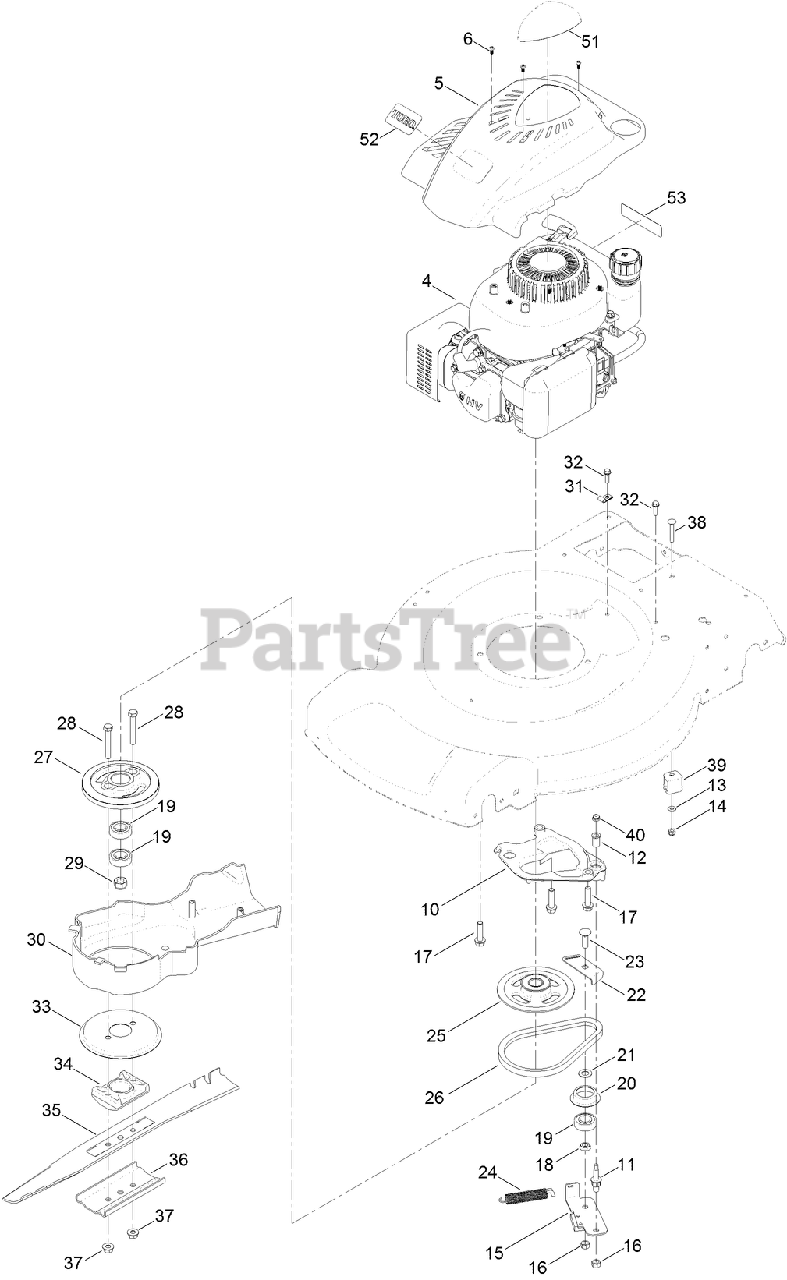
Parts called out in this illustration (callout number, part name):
4	ENGINE-1P65FC
5	SHROUD
6	SCREW-PPH
10	PLATE-ANCHOR
11	BOLT-SHOULDER
12	BUSHING
13	WASHER-FLAT
14	NUT-LOCK, NI
15	PLATE-BRAKE
16	NUT-HEX
17	SCREW-HWH
18	SPACER-BEARING
19	BEARING-BALL
20	RETAINER-BELT
21	SPACER
22	PLATE-GUIDE
23	BOLT-CARR
24	SPRING-TENSION, BRAKE
25	PULLEY
26	BELT
28	SCREW-HH
29	NUT-HEX
31	CLIP-CLOSED, INSULATED
32	SCREW-HWH
33	DISC
34	SUPPORT-BLADE
35	BLADE-22 INCH
36	SUPPORT-BLADE
37	NUT-FLANGE, LOCK
38	SCREW-CARR
39	ANCHOR-CABLE
40	NUT-HF
51	DECAL-SHROUD
53	DECAL-ARRESTER, SPARK
